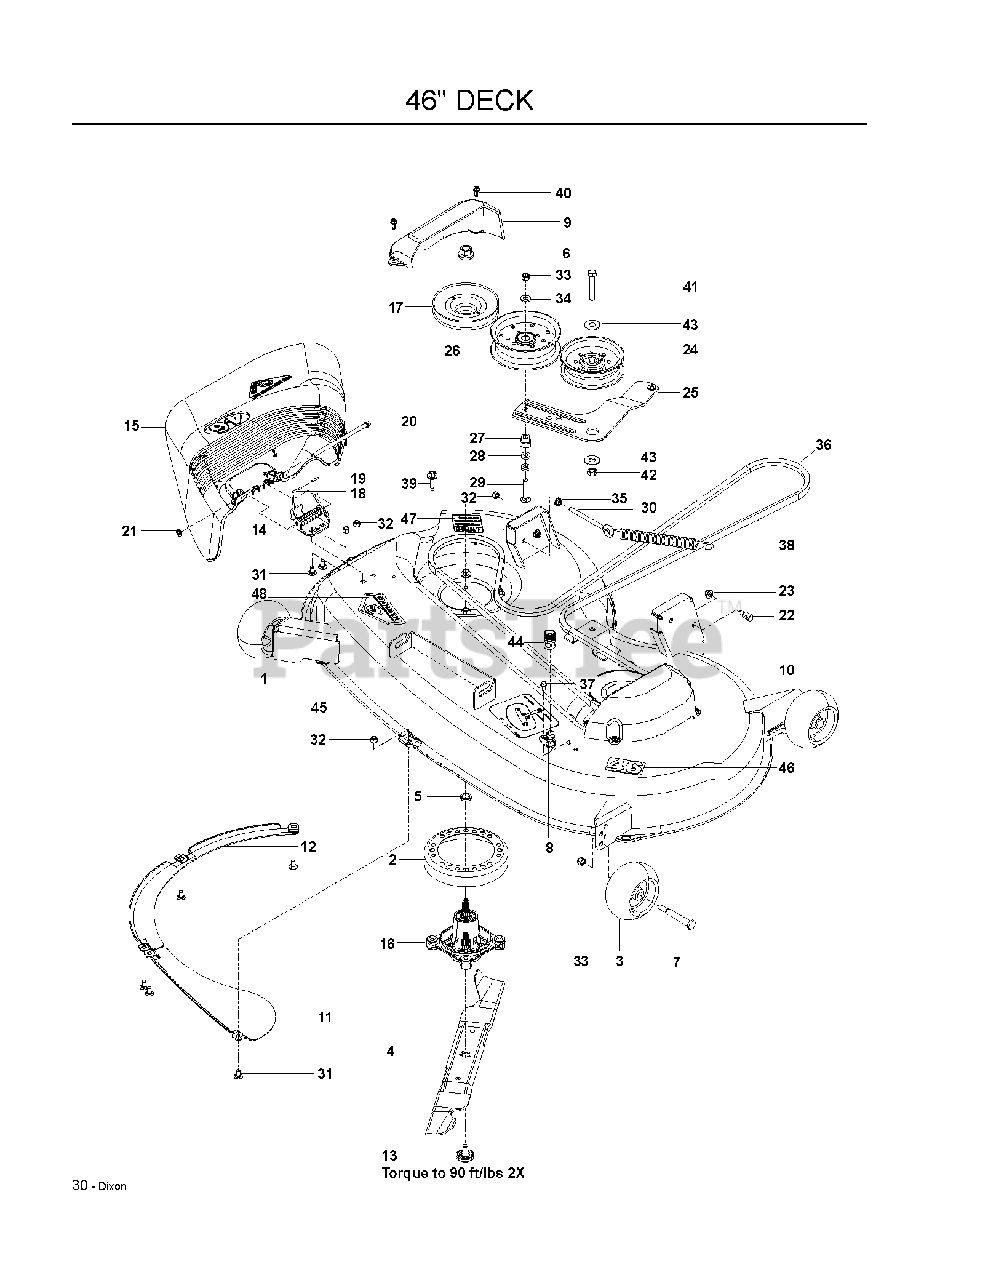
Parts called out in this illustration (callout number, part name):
1	DECK.STAMPED.46".W/DECALS.BLUE
2	STRIPPER-ROUND-UNIVERSAL
3	GAUGE WHEEL
4	BLADE, 46" HI-LIFT
5	WASHER-SPACER
6	LOCKNUT - 9/16
7	SHOULDER BOLT 1/2X2-5/8 ZD SPE
8	PORT.WASHOUT
9	COVER.MANDREL.RH.46"
10	COVER.MANDREL.LH.46"
11	BAFFLE CENTER FRONT
12	BAFFLE FRONT RH
13	BOLT.WASHER.ASM.7/16-2
14	BRKT.DEFLECTOR.38"2005+
15	SHIELD.DEFLECTOR.MOWER.46"BLAC
16	CUTTER HOUSING
17	PULLEY, DECK
18	TORSION SPRING
19	CAP-SLEEVE
20	ROD, HINGE
21	PUSH NUT
22	STUD.FASTNER.W/ANTI-ROTATE
23	5/16-18 NYLOC FLANGE NUT
24	PULLEY.IDLER.MWR.STATIONARY.LH
25	ARM.IDLER
26	PULLEY, IDLER
27	IDLER BUSHING
28	WASHER 3/8 X 3/4 X .187 TK
29	RHSNB 3/8C X 2
30	EYE BOLT 4.5`
31	CARRIAGE BOLT 5/16C X 5/8"
32	NUT 5/16 NYLOC
33	NUT 3/8-16 NYLOC
34	WASHER 3/8 SAE FLAT
35	NUT 5/16C WHIZ
37	BOLT 1/4-20 X 1/2 HWST
38	SPRING, DECK BELT
39	WASHER HEAD SCREW
40	SCREW- 1/4-20 X 5/8
41	BOLT 7/16-14 X 2-1/2 GR 5 ZD
42	7/16-14 HEX NUT W/NYL RING ZD
43	WASHER 7/16 FLAT ZD
44	COUPLING.QUICK CONNECT
45	DECAL, BELT ROUTING
46	DECAL, 46"
47	DECAL, CAUTION
48	DECAL, CPSC
